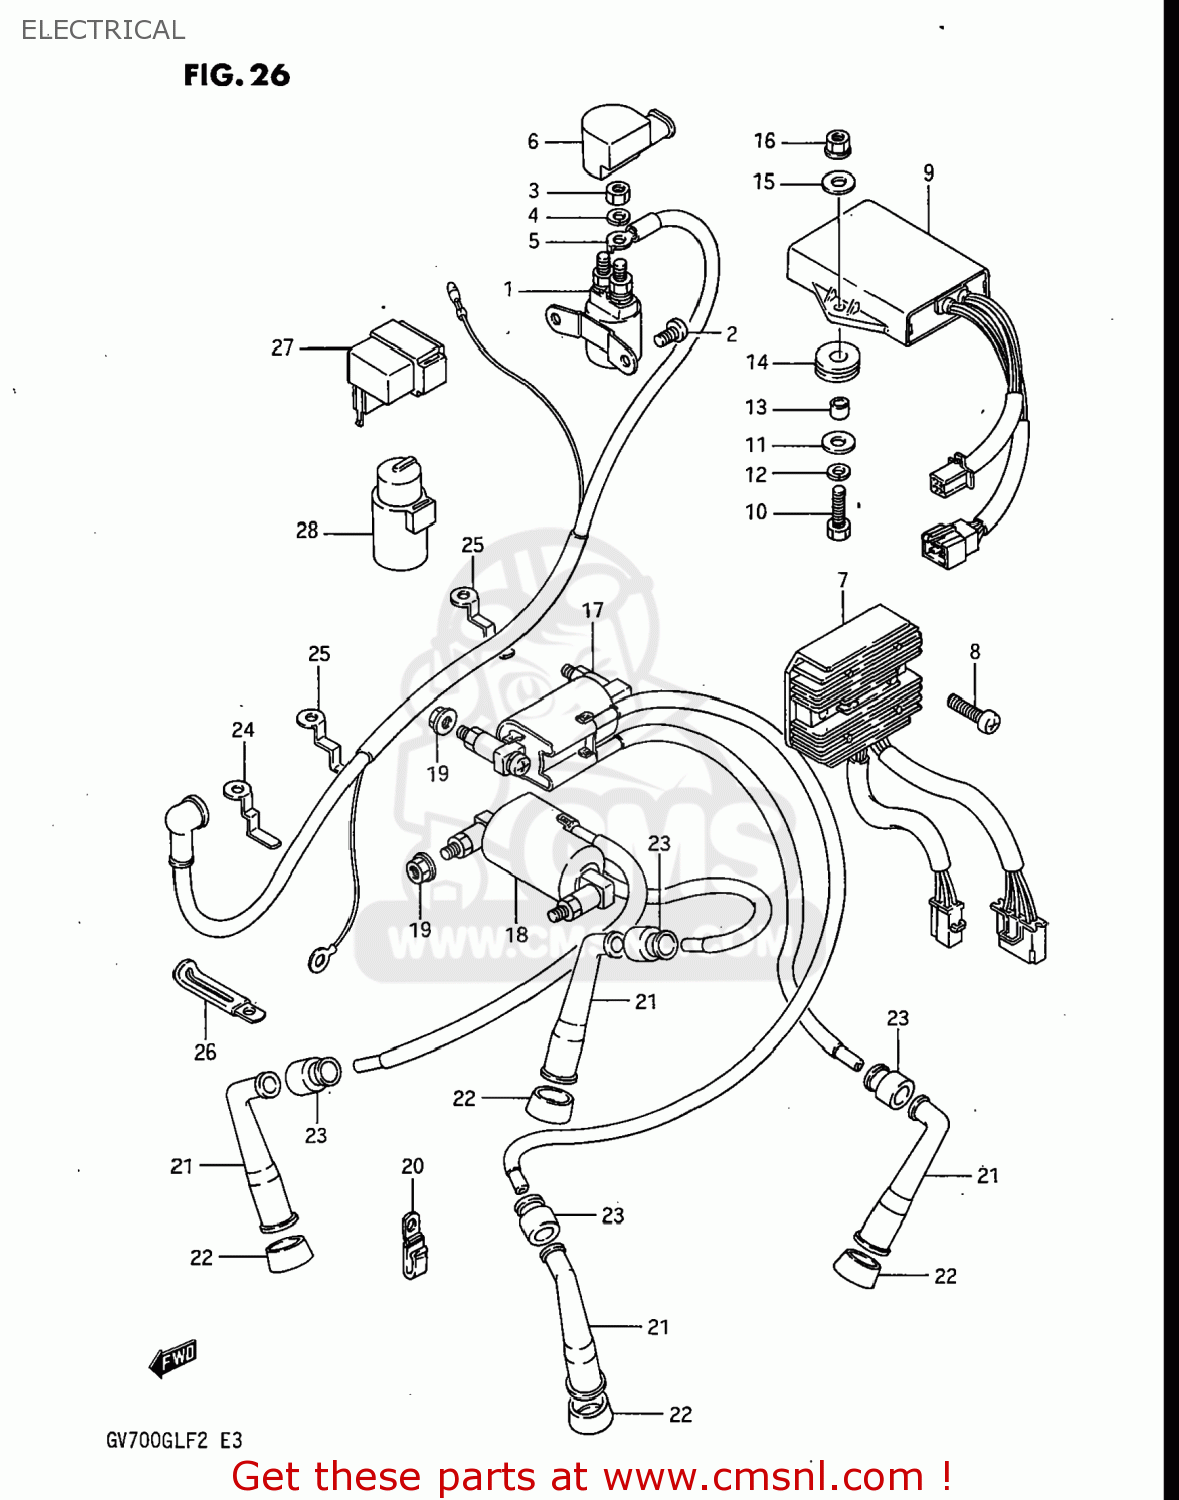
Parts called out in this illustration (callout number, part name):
1	RELAY ASSEMBLY,STARTING MOTOR
2	SCREW
3	NUT
4	WASHER,LOCK
5	WIRE,STARTER MOTOR
6	CAP,STARTER RELAY TERMINAL
7	RECTIFIER ASSY
8	SCREW
9	IGNITER ASSEMBLY
10	BOLT
11	WASHER
12	LOCK WASHER
13	SPACER
14	CUSHION
15	WASHER
16	NUT
17	COIL ASSEMBLY,IGNITION
18	COIL ASSEMBLY,IGNITION
19	NUT
20	CLAMP
21	CAP ASSY,SPARK PLUG
22	SEAL,SPARK PLUG
23	SEAL,SPARK PLU
24	CLAMP,WIRING HARNESS
25	CLAMP,WIRING HARNESS
26	CLAMP
27	CIRCUIT,OPENING RELAY
28	RELAY ASSEMBLY,THERMOMETER
